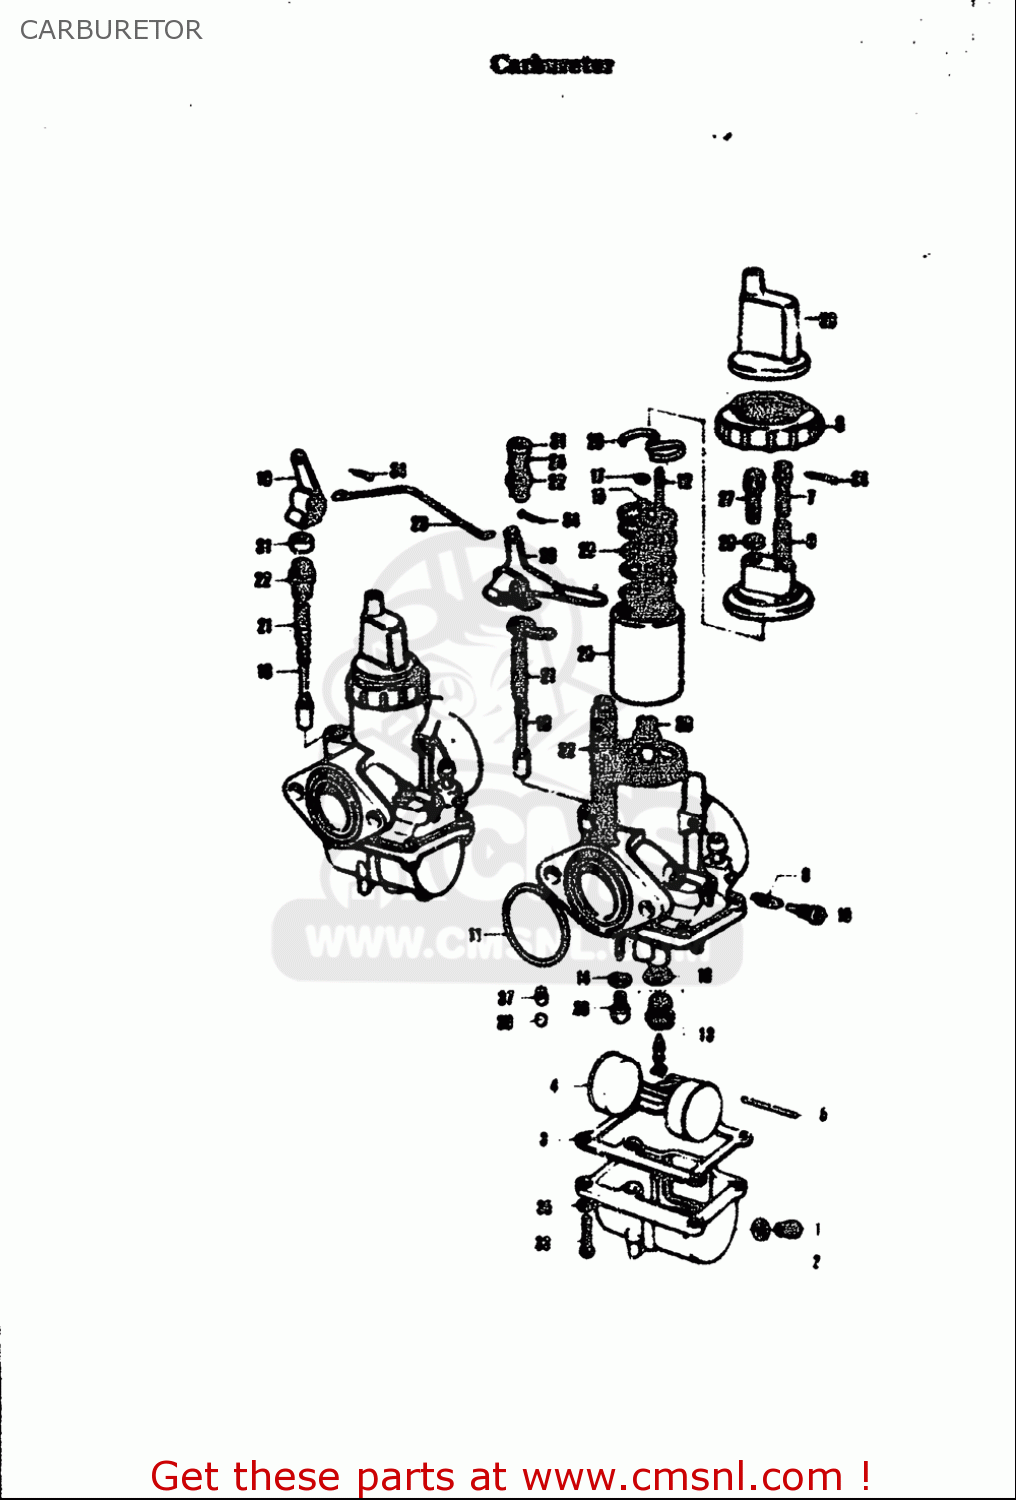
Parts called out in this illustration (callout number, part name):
1	PLUG
2	GASKET,DRAIN,PLUG (NAS)
3	GASKET,FLOAT CAHMBER (NAS)
4	FLOAT
5	PIN,FLOAT
7	SCREW,THROTTLE VALVE ADJUST
8	SPRING
9	SPRING,THROTTLE SCREW
10	SCREW,PILOT AIR
11	O RING(D:3.5,ID:31.7)
12	ROD,THROTTLE VALVE ADJUST
13	VALVE ASSY,NEEDLE
14	WASHER
16	GASKET,MAIN JET HOLDER (NAS)
17	CLIP
18	PLUNGER,STARTER
21	SPRING
23	ROD,STARTER LEVER
27	ADJUSTER,CABLE
29	NUT
31	CAP,PLUNGER
33	SCREW 4X16
35	WASHER,LOCK
36	JET,MAIN(170)
37	JET,PILOT(30)
38	JET
